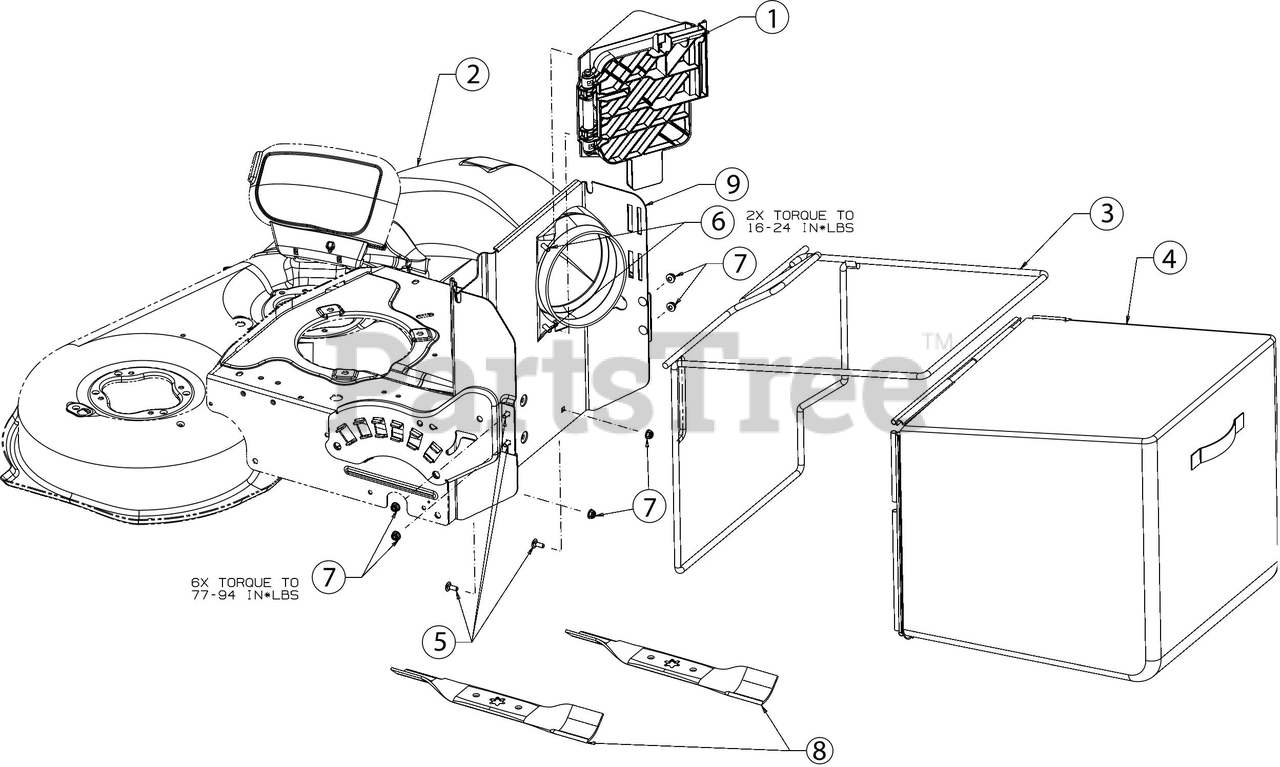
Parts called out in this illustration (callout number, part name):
1	GRASSBAG DOOR ASSEMBLY
1	PUSH CAP
1	CHUTE HINGE PIN
2	CHUTE ASSEMBLY
2	FLANGE LOCK NUT
2	SCREW 1/4-20 x .620 GR5
2	FLAT WASHER .28 ID x .74 OD x .063
4	GRASSBAG - TROY-BILT 28" MOWER
4	GRASSBAG - PLAIN 28" MOWER
5	CARRIAGE BOLT 1/4-20 x .62
6	SCREW 1/4 x .750
7	FLANGE LOCK NUT
8	BLADE (HI LIFT) (14.2)
